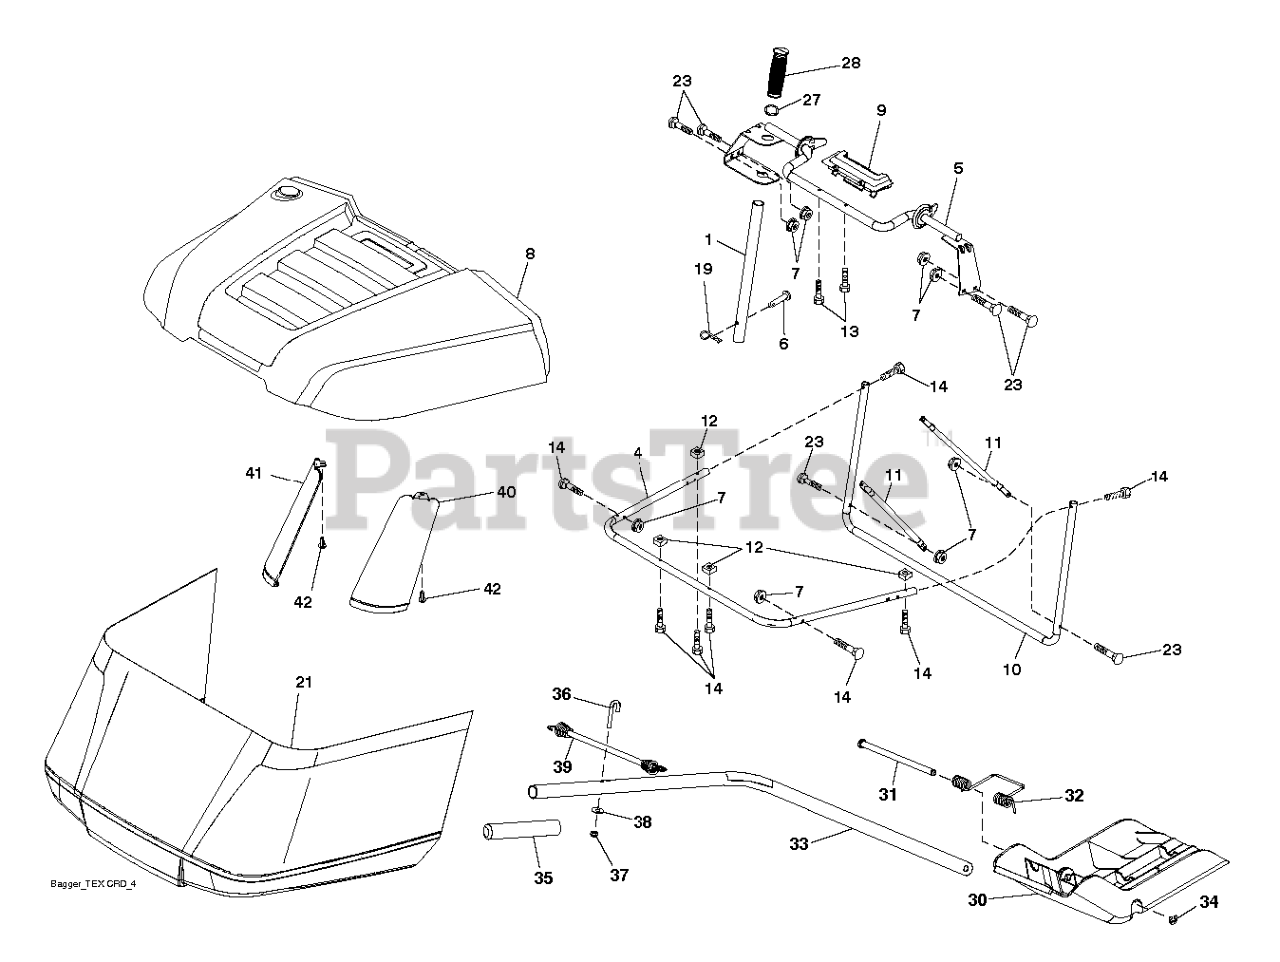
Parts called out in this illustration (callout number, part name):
1	TUBE.HANDLE.BAGGER.CRD/SRD.BLA
4	SUBASM.TOP.TUBE.TEX.CRD
5	FRAME.ASM.TOP.BAGGER.SRD
6	RIVET,DRILLED
7	NUT T
8	BAGGER.TOP.SUB.ASSEM.SRD
9	INSERT.HANDLE.BAGGER.(2 2)
10	FRAME FRAME.FRONT.TEX.CRD
11	BRACE BRACE SIDE TUBE
12	NUT.SQUARE.1/4
13	SCREW.1/4X1.150.HXWSH
14	BOLT.SHOULDER.HX.WSH.1/4X1.150
19	PIN.COTTER.5/16.BOW TI
27	RB GROMMET.RUBBER.SRD
28	GRIP.HANDLE.BLACK
30	PLUG PLUG
31	PIN PIN.HINGE
32	SPRING SPRING DOUBLE TORSION
33	SHAFT SHAFT TEX CRD MULCH PLU
34	E-RING.5/16"
35	GRIP GRIP MULCH PLUG HAND
36	BOLT BOLT J
39	BUBGEE BUBGEE TEX CRD
42	CLIP CHRISTMAS TREE CLIP
